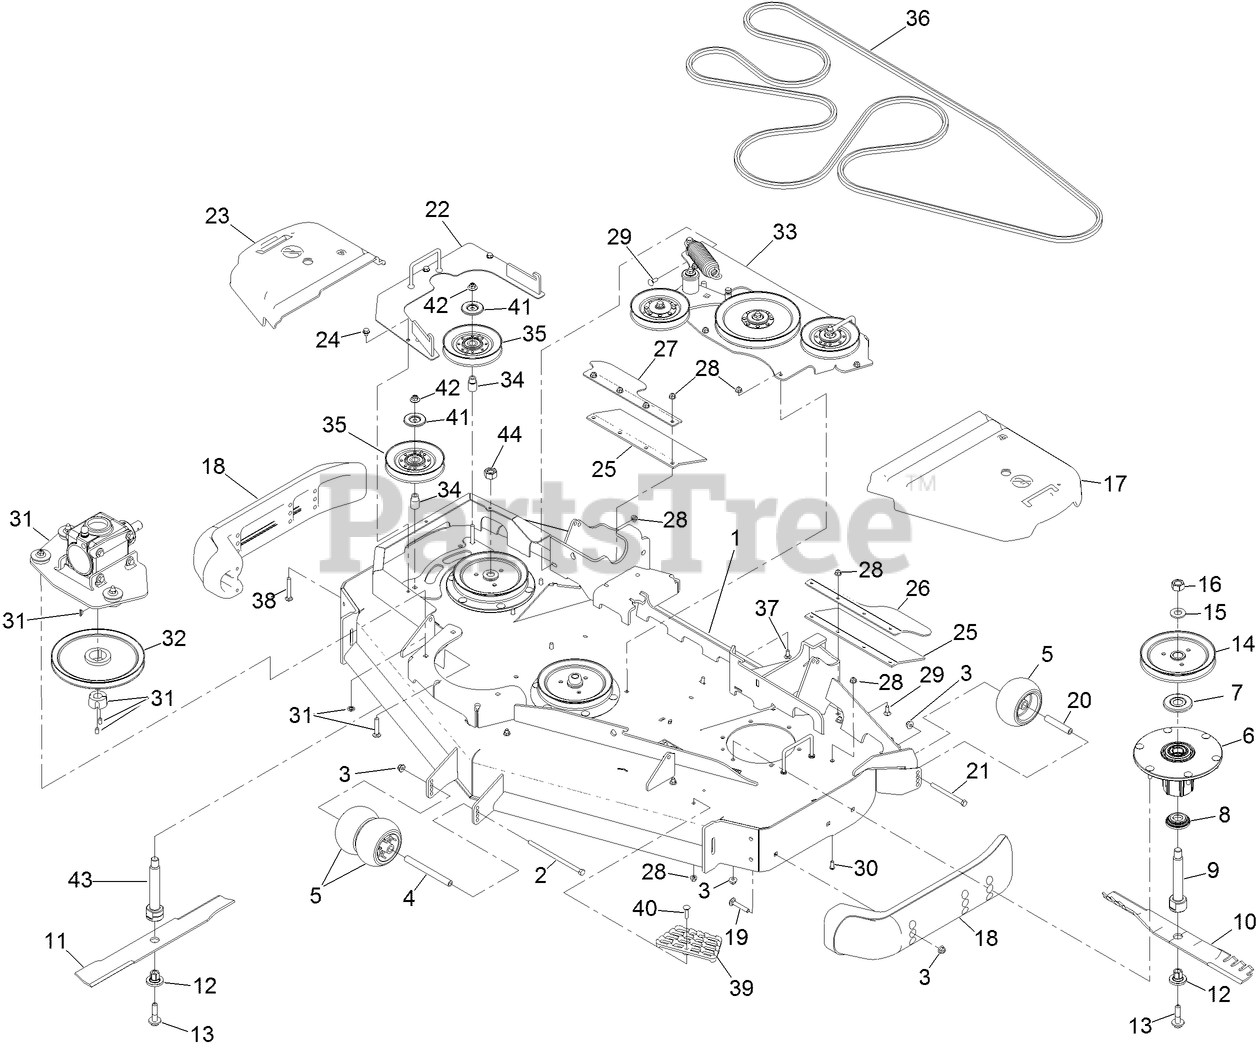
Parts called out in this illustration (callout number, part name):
1	DECK DECAL ASM
2	SCREW-HH
3	NUT-HF, NI
4	SPACER-WHEEL
5	ROLLER-SCALP, ANTI
6	SPINDLE ASM
7	GUARD-BEARING, TOP
8	GUARD-BOTTOM
9	SHAFT-SPINDLE
10	BLADE-20.50 ATOMIC
11	BLADE-20.50 CR LOW FLOW
12	BUSHING-HEX
13	SCREW-SEMS
14	SHEAVE-DRIVE, BLADE
15	WASHER
16	NUT-HEX
17	COVER-BELT, LH
18	SKID-BUMPER, DECK
19	SCREW-CARR
20	TUBE-SPANNER
21	SCREW-HH
22	COVER-DRIVE REVERSE
23	COVER-BELT, RH
24	SCREW
25	GUARD-TIRE
26	SUPPORT-FLAP, OUTER (LH)
27	SUPPORT-FLAP, OUTER (RH)
28	NUT-HF, NI
29	SCREW-CARR
30	SCREW-HSBH
31	GEARBOX ASM
32	PULLEY
33	IDLER MOUNT ASM
34	STANDOFF-IDLER
35	IDLER V
36	BELT-BB
37	SCREW-CARR
38	SCREW-CARR
39	STEP-DECK
40	SCREW-CARR
41	SHIELD-DUST
42	NUT-FLANGE, NI
43	SHAFT-SPINDLE, INT. HEX LH THD
44	NUT-HEX,LH,LOCK
